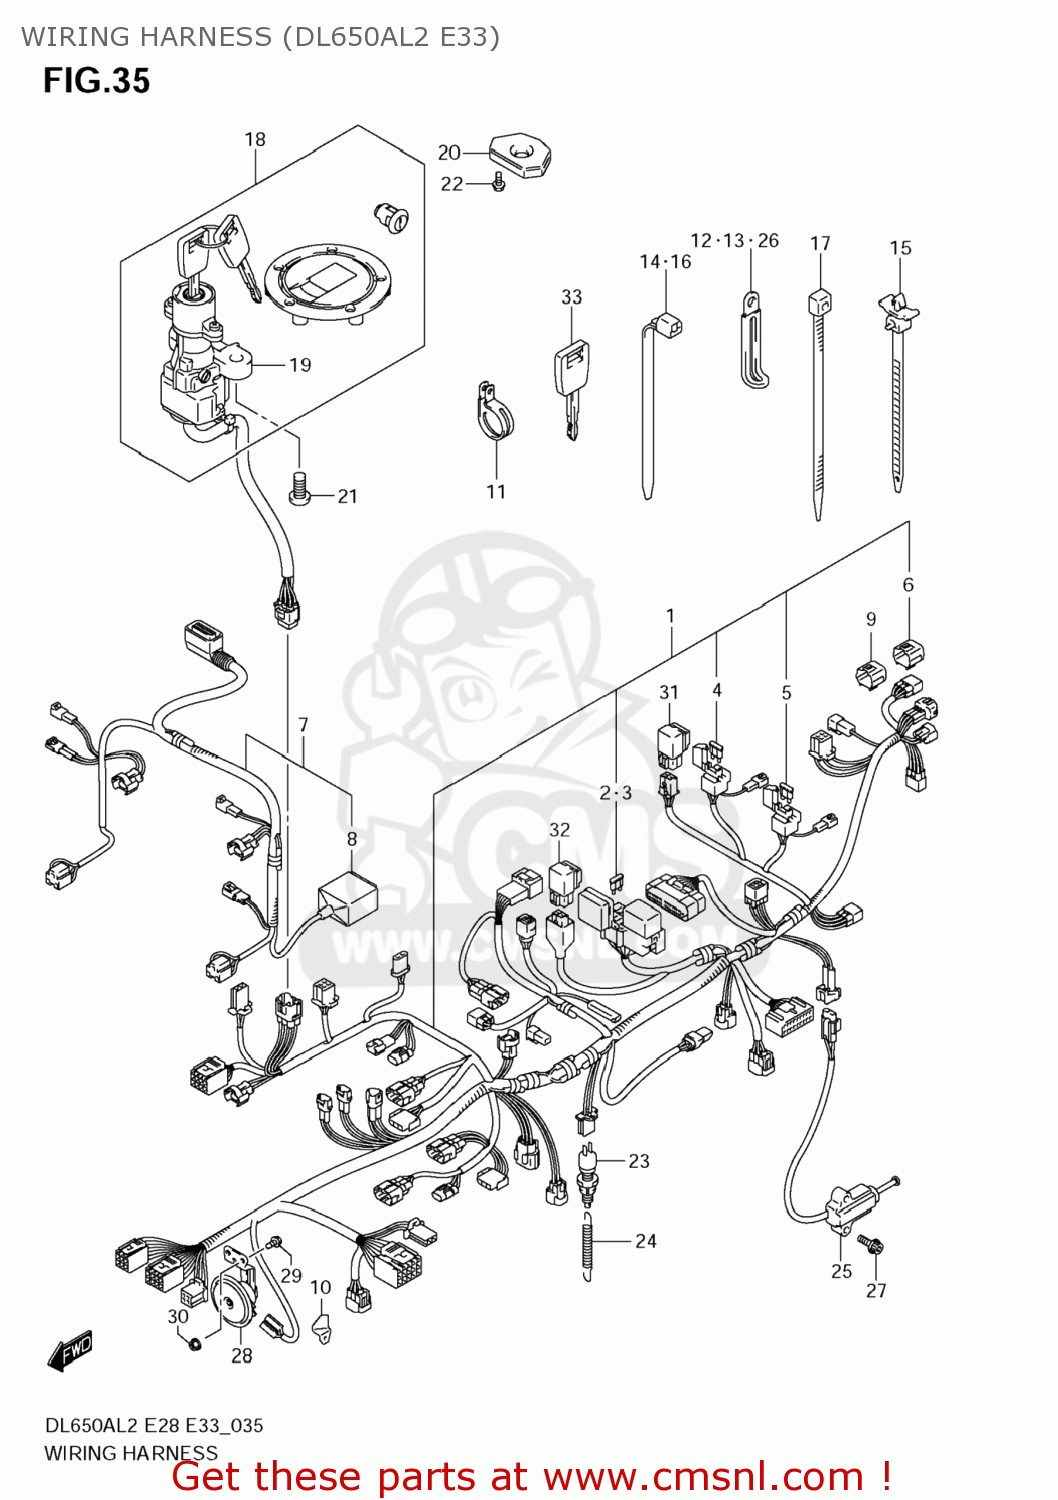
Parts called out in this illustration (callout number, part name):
1	HARNESS,WIRING NO.1
2	FUSE(10A)
3	FUSE(15A)
4	FUSE(15A)
5	FUSE(25A)
6	CAP,CO ADJUST
7	HARNESS,WIRING NO.2
8	COVER,CONNECTOR
9	CAP,TS
10	GUIDE,WIRING HARNESS
11	CLAMP
12	CLAMP(L:45)
13	CLAMP(L:80)
14	CLAMP(L:125)
15	CLAMP(L:120)
16	CLAMP(L:165)
17	CLAMP(L:145)
18	LOCK SET
19	LOCK ASSY,STEERING
20	COVER,STEERING LOCK
21	BOLT(8X20)
22	BOLT
23	SWITCH ASSY,STOP LAMP
24	SPRING
25	SWITCH ASSY,SIDE STAND
26	CLAMP(L:45)
27	BOLT
28	HORN ASSY
29	BOLT(6X16)
30	NUT
31	RELAY ASSY
32	RELAY ASSY
33	KEY,BLANK
